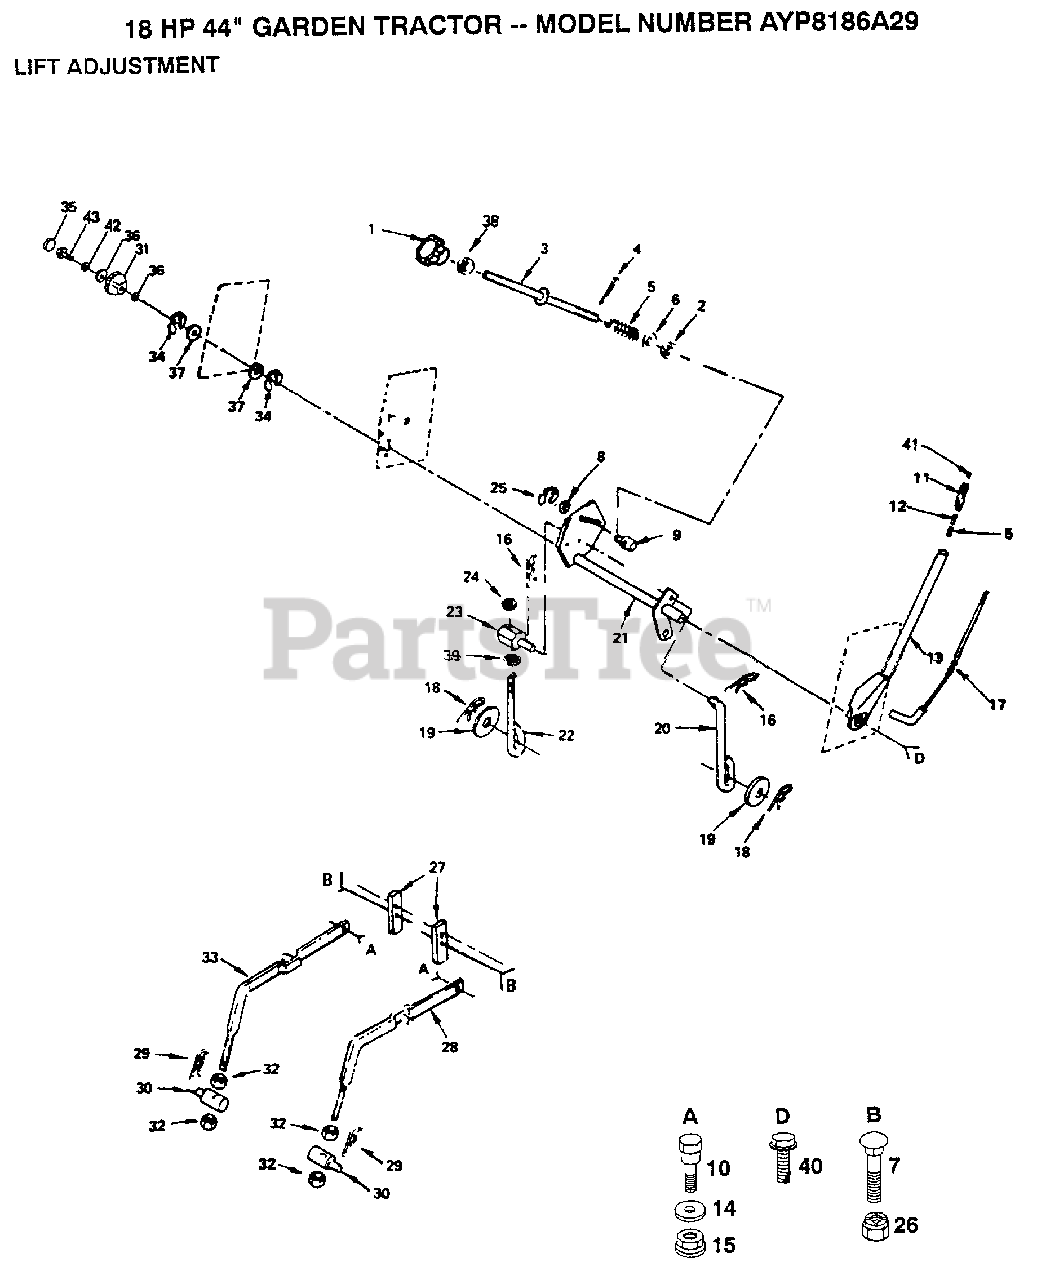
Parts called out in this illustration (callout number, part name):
2	NUT T
3	ROD LIFT LT
5	SPRING T
6	WASHER
8	WASHER
9	TRUNION LT
10	"BOLT, SHOULDER LT"
11	GRIP
14	WASHER T
15	NUT SPECIAL T
17	LEVER ROD LT
18	SPRING.RETAINER
20	LIFT LINK LT
22	PIVOT PIN T
25	KLIP RING
27	UPSTOP
28	RH SUSP ARM ASM
29	SPRING H
31	HEIGHT INDICATOR
32	NUT
33	LH SUSP ARM ASM
34	E-RING
35	"PLUG,HOLE"
36	WASHER
37	WASHER
38	NUT
39	NUT
40	"BOLT,HEX"
42	LOCKWASHER
